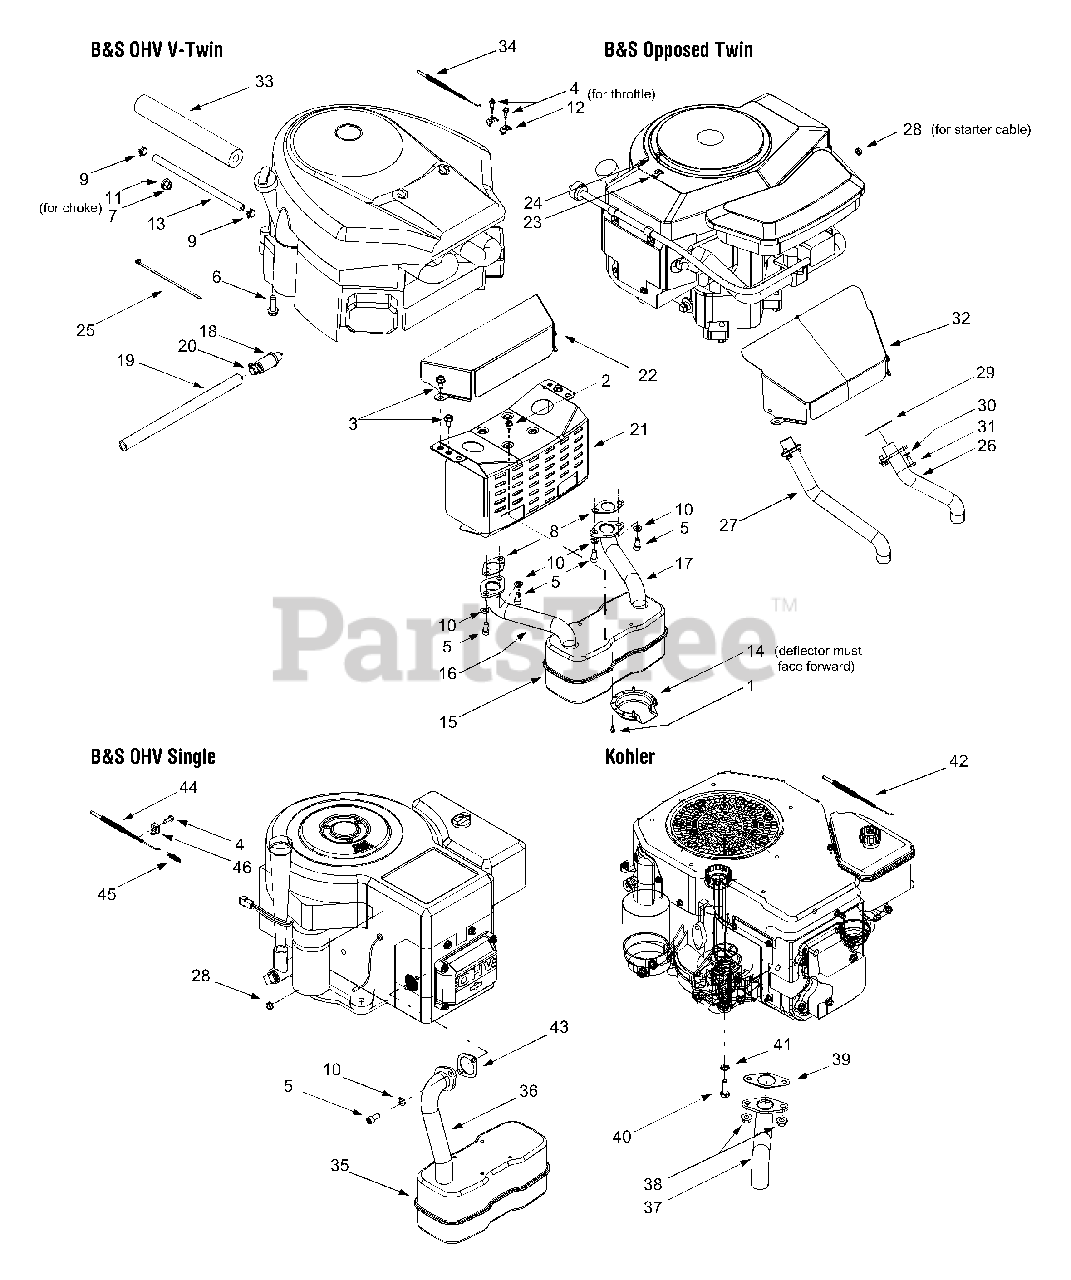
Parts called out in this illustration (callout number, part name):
1	Self-tapping Screw, #8-18 x .50
2	Self-tapping Screw, 1/4-20 x .50
3	Self-tapping Screw, 5/16-18 x .625
4	Screw, #10-32 x .625 (B&S OHV V-Twin)
5	Socket Cap Screw, 5/16-18 x .625
6	Self-tapping Screw, 3/8-16 x 1.25
7	Hex Nut, 3/8-16
8	Exhaust Gasket (B&S OHV V-Twin)
9	Hose Clamp
10	Lock Washer, 5/16
11	Lock Washer, .406 x .875 x .059
12	Casing Clamp (B&S OHV V-Twin)
13	Fuel Line Hose
14	Muffler Deflector
15	Muffler, Twin Inlet (B&S Opposed Twin & OHV V-Twin)
16	RH Exhaust Pipe (B&S OHV V-Twin)
17	LH Exhaust Pipe (B&S OHV V-Twin)
18	Oil Drain Valve
19	Oil Drain Hose
20	Oil Drain Cap
22	Engine Heat Shield (B&S OHV V-Twin)
23	Clamp, 9/16 (B&S Opposed Twin)
24	Screw, #10-16 x .5 (B&S Opposed Twin)
25	Cable Tie
26	LH Exhaust Pipe (B&S Opposed Twin)
27	RH Exhaust Pipe (B&S Opposed Twin)
28	Hex Sems Nut, 1/4-20 (B&S Opposed Twin & OHV Single)
29	Exhaust Gasket (B&S Opposed Twin)
30	Lock Washer, 1/4 (B&S Opposed Twin)
31	Hex Screw, 1/4-20 x .750 (B&S Opposed Twin)
33	Foam, .625 x 1.5 x 10 (fits over fuel line)
34	Throttle Cable (B&S Opposed Twin & OHV V-Twin)
35	Muffler, Single Inlet (B&S OHV Single & Kohler)
36	Exhaust Pipe (B&S OHV Single)
37	Exhaust Pipe (Kohler)
38	Flange Nut, 8mm (Kohler)
39	Exhaust Gasket (Kohler)
40	Hex Cap Screw, 8mm (Kohler)
41	External Lock Washer (Kohler)
42	Throttle Cable (Kohler)
43	Exhaust Gasket (B&S OHV Single)
44	Throttle Cable (B&S OHV Single)
45	Extension Spring, .275 x 1.25 (B&S OHV Single)
46	Casing Clamp (B&S OHV Single)
